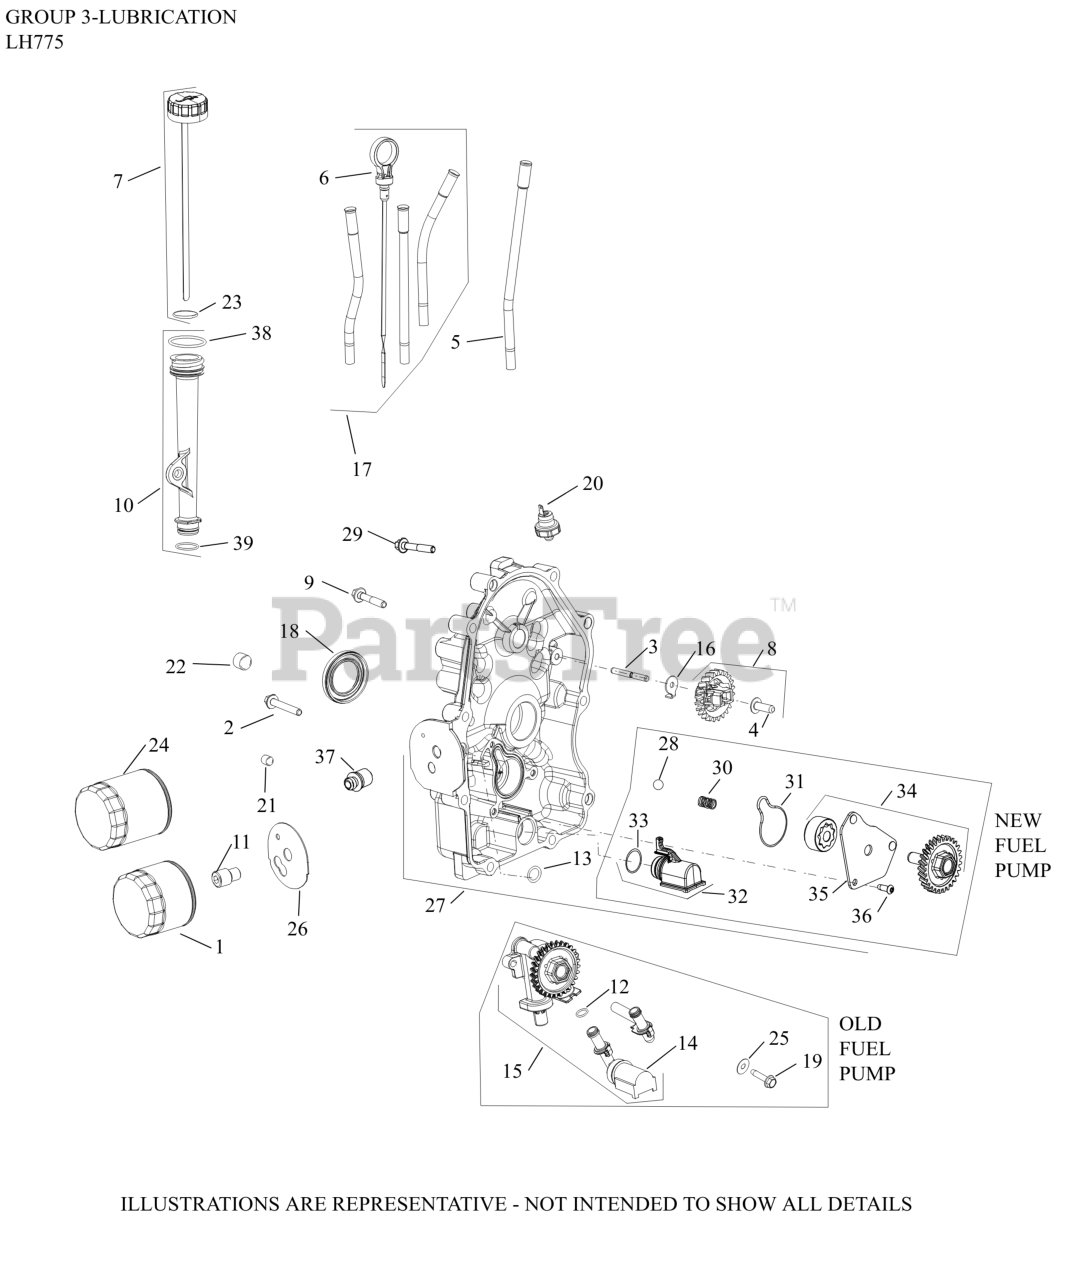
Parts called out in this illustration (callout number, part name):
1	OIL FILTER
3	SHAFT, GOVERNOR GEAR
4	PIN, GOVERNOR REGULATING
8	KIT, GOVERNOR GEAR W/PIN
9	SCREW, FLG M8X1.25X45
11	NIPPLE, OIL FILTER
16	TAB, LOCKING
17	KIT, DIPSTICK/DIPSTICK TUBES
20	SENSOR, OIL PSI
21	PLUG, CTSK PIPE 1/8"
27	KIT, CLOSURE PLATE ASSY
28	PRESSURE RELIEF BALL
29	SCREW, HEX FLANGE
30	SPRING, COMPRESSION
31	SEAL, OIL PUMP COVER
32	PICK-UP ASSEMBLY, OIL
33	O-RING, OIL PICK-UP
34	PUMP ASSEMBLY, OIL
35	COVER, OIL PUMP
36	SCREW, BUTTON HEAD
